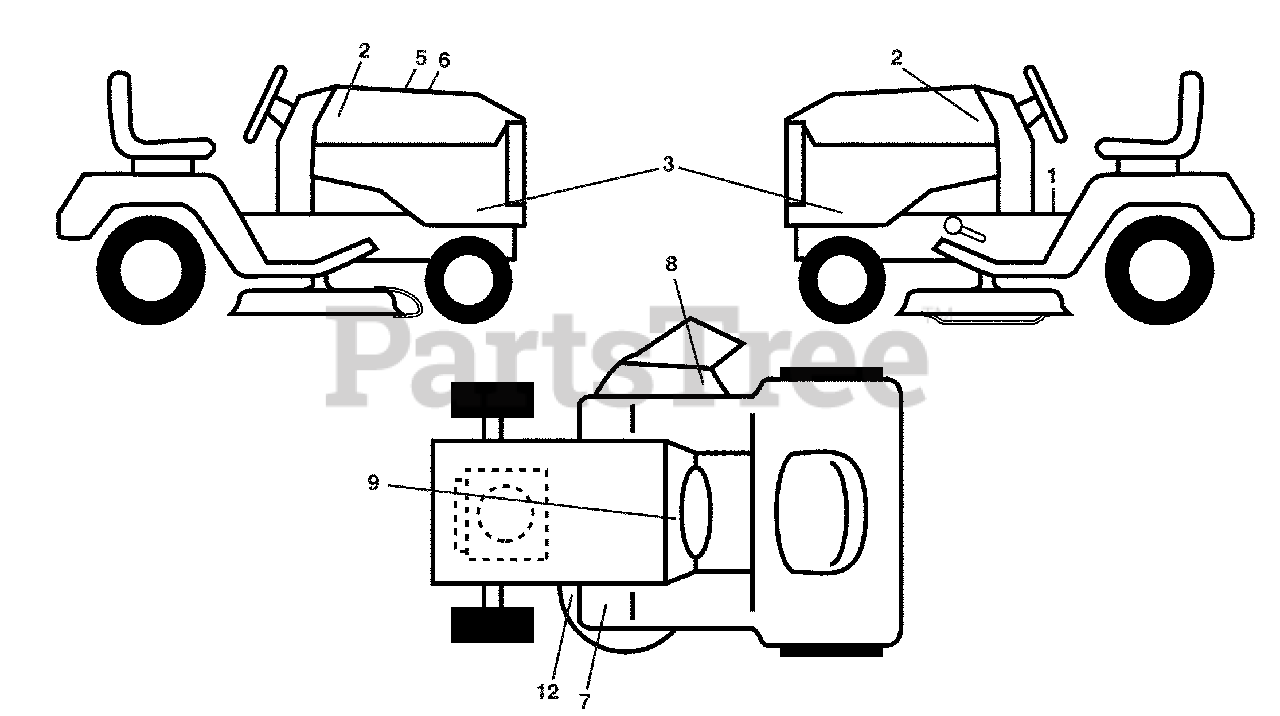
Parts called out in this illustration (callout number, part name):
1	Decal, Operators
2	Decal, Emblem
3	Decal, Emblem Panel SD
5	Decal, Customer Respons.
6	Decal, Replacement
7	Decal, Pedal Husq. Crown
8	Decal Mower Warn Keep Hand away
9	Decal, Battery Dnge/Poi
12	Decal, Mower V-Belt Schematic
